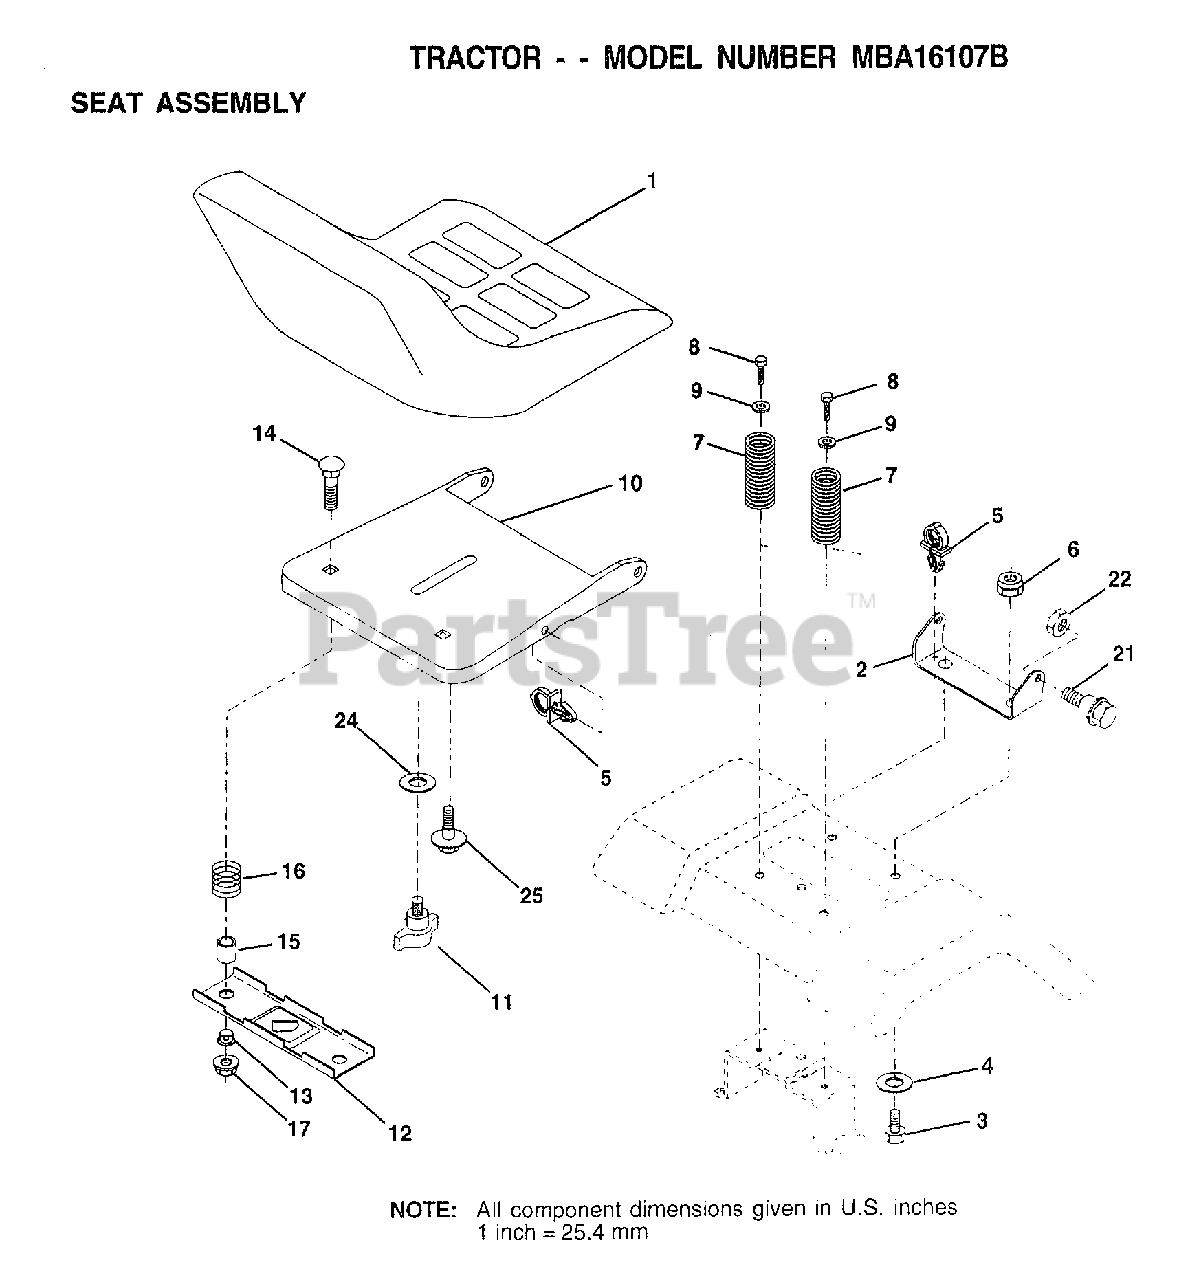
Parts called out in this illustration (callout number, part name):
1	SEAT.2400/1416.BK
2	BRACKET PVT SEAT
3	BOLT
4	WASHER PM
5	CLIP.PUSH-IN.HING
6	NUT
7	SPRING COMPRESSIO
8	SCREW
9	WASHER
10	PAN-SEAT
11	KNOB.SEAT.ADJ.WINGNUT
12	BRKT SWITCH
13	BUSHING
14	BOLT-RD HD SQ NK
15	SPLIT SPACER
16	SPRING
21	BOLT
22	NUT
24	WASHER
25	"BOLT,SHOULDER"
